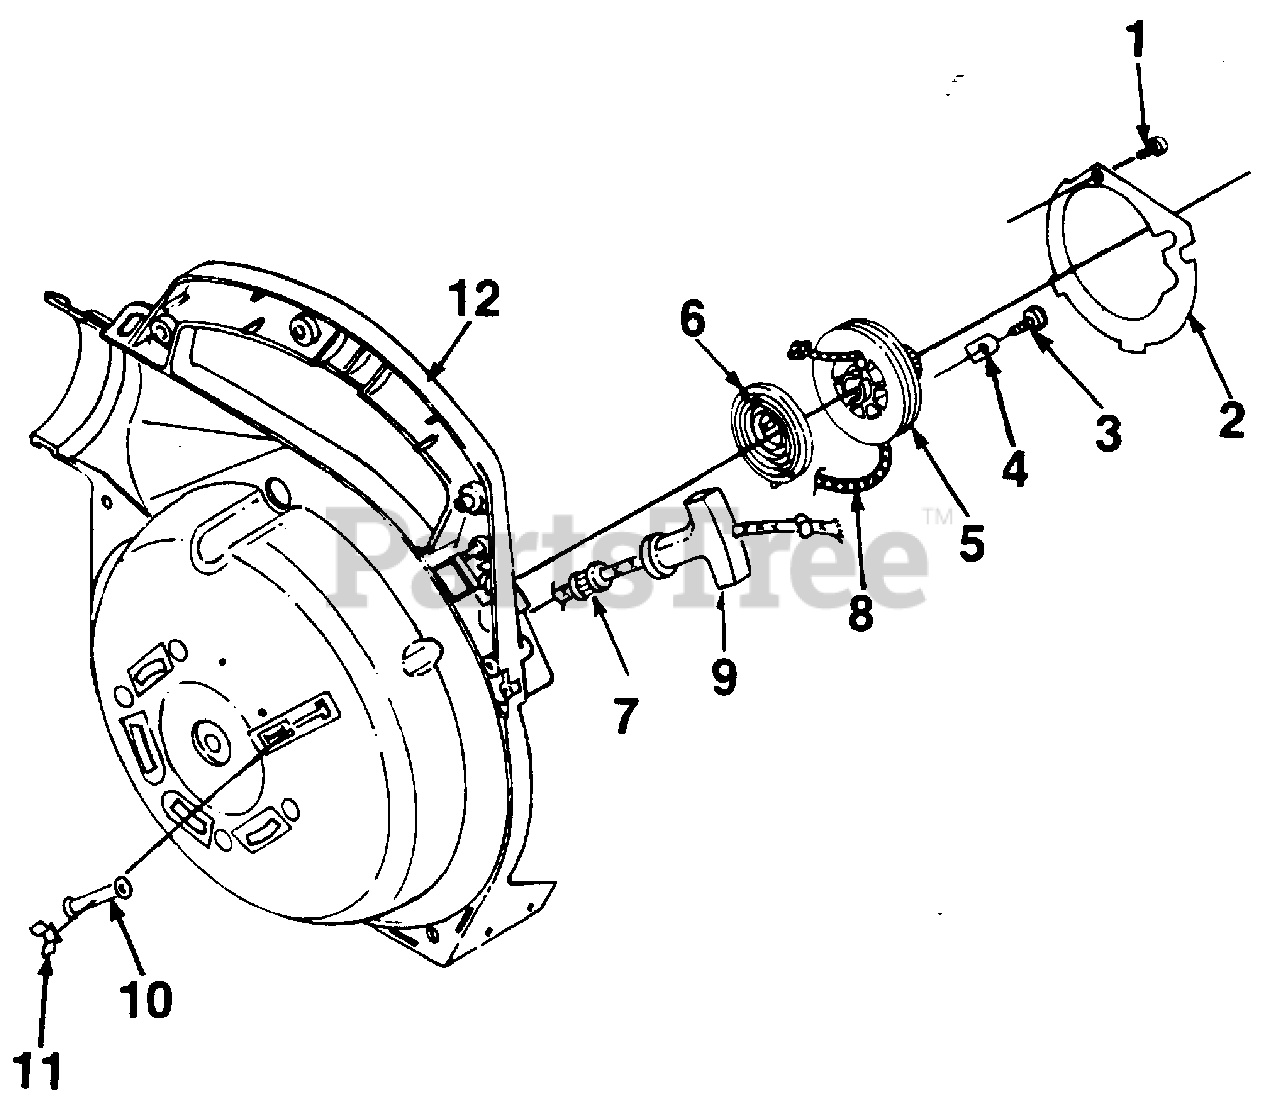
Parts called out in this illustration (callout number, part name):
1	SCREW- Thread Forming (#6-19 x 3/4 lg.)
2	PLATE- Rotor
3	SCREW- Thd. forming 10 x 1/2
4	BRACKET- Retaining
5	PULLEY- Starter
6	SPRING & CONTAINER
7	BUSHING- Starter
8	ROPE- Starter 46"
9	GRIP- Starter rope
10	BUSHING- Starter rope
11	CLIP- Retainer
12	HOUSING- Volute (inner)
